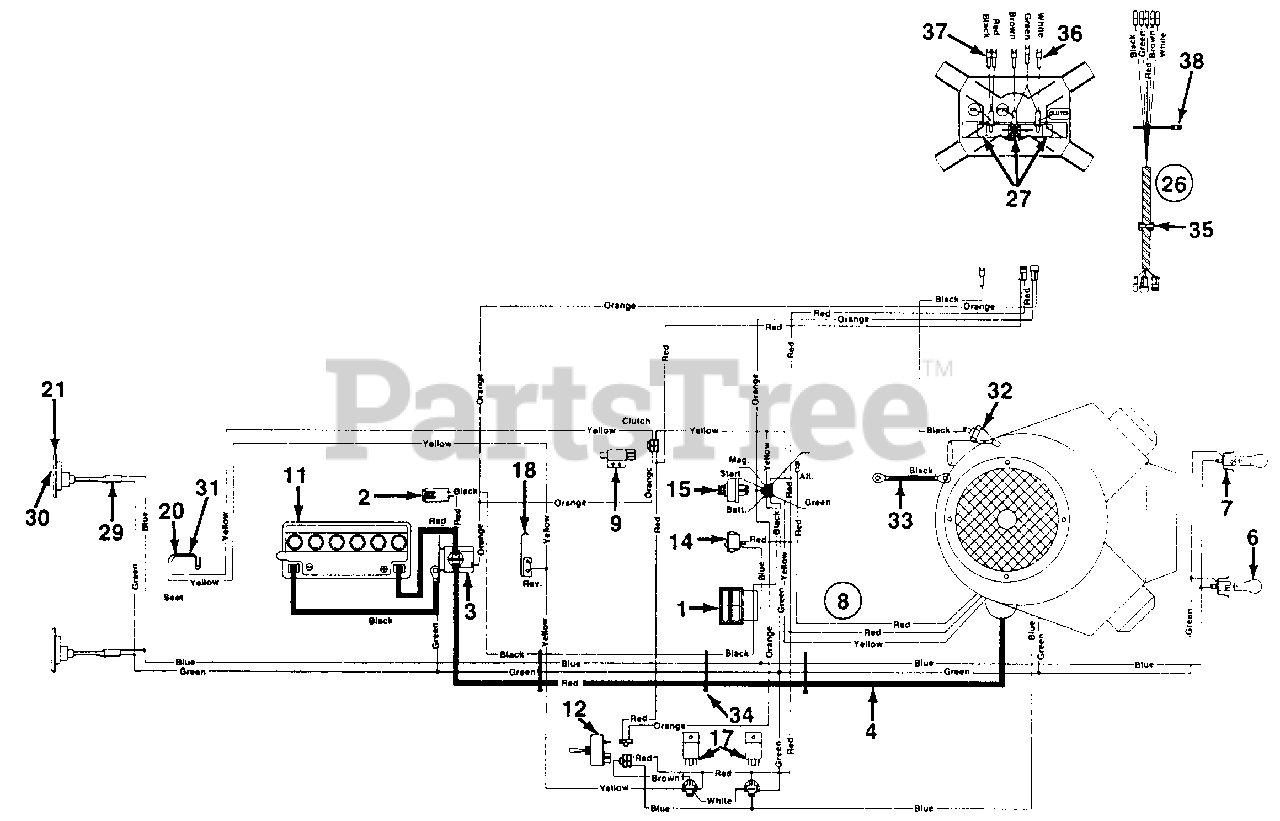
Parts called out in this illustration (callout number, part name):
1	Ammeter
2	Fuse 20 Amps
3	Solenoid
4	Wire 30" Lg.
6	Bulb
7	Socket
8	Wire Harness
9	Safety Switch (Clutch)
11	Battery 12V (275 Cold Crank Amps)
12	Switch (PTO)
14	Light Switch
15	Ignition Switch
17	Relay
18	Spring Lever
20	Safety Switch (Seat)
21	Taillight
26	Monitor Shaft Harness
27	Bulb
29	Taillight Harness
31	Safety Switch (Seat)
32	Oil Pressure Switch
33	Wire 7.5" Lg.
34	Cable Tie
35	Wire Clip
36	Monitor Light Harness Dual
37	Monitor Light Harness Single
38	Cable Tie
